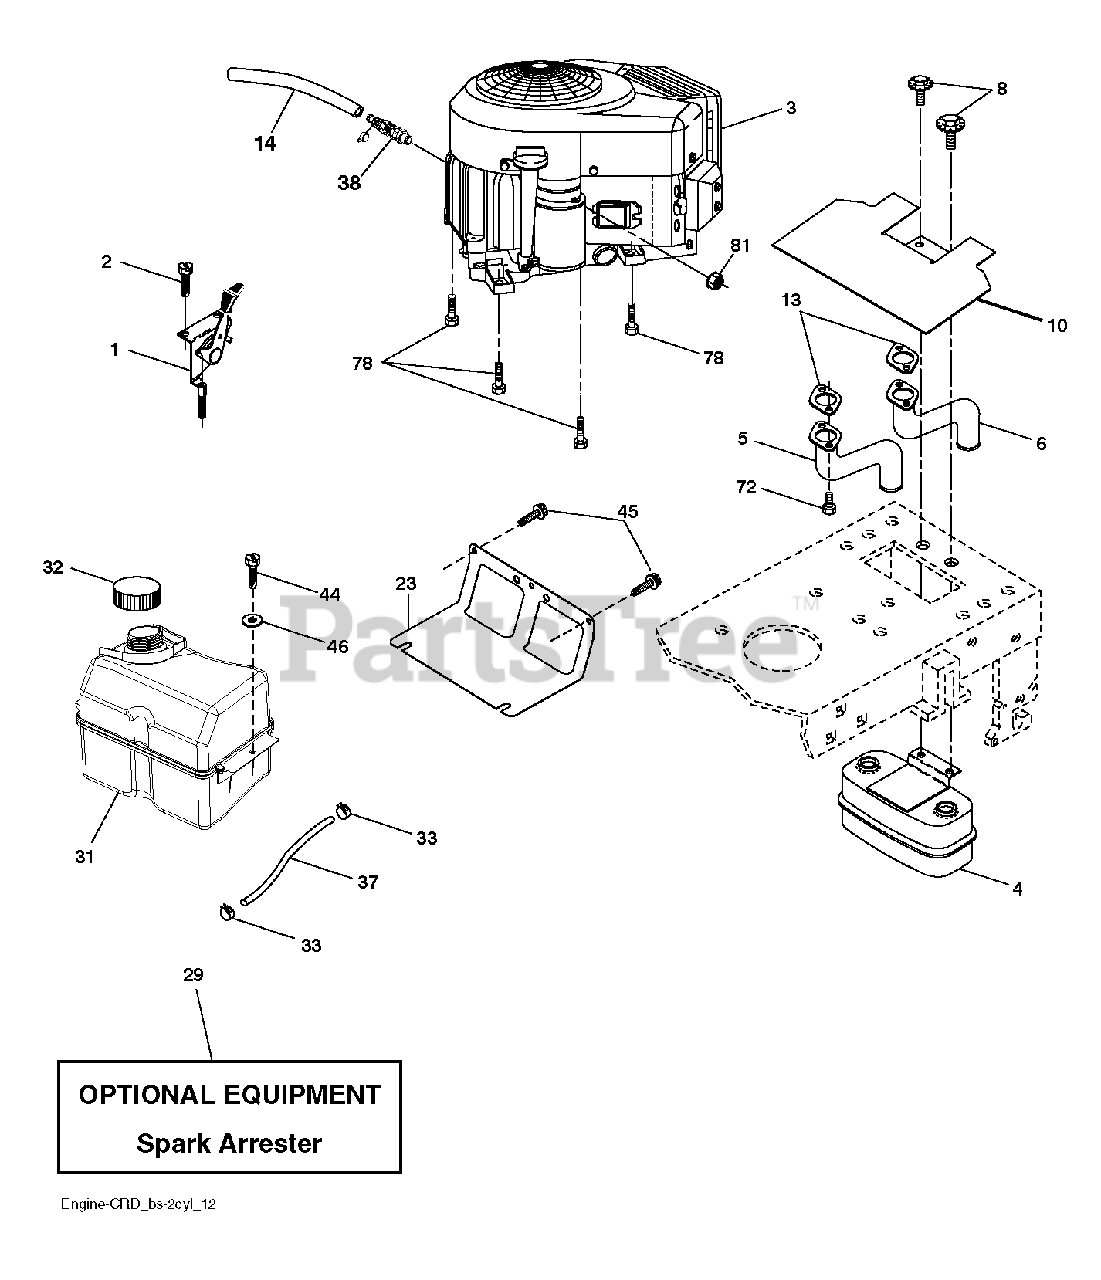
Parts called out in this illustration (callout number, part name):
1	CONTROL.TH/CK.COBRA.B&S.TWN.
2	SCREW.#10 X 0.750.BOS THREAD
4	MUFFLER.TWIN.CYL.LOW.TONE
5	EXHAUST TUBE RH
6	TUBE MANIFOLD LH
8	BOLT, 5/16-18 X 1 3/4
10	SHIELD.HEAT.MUFFLER
13	GASKET.MUFFLER
14	TUBE, DRAIN OIL ASM.
23	SHEILD.BROWNING.DBR.GUARD
29	ARRESTER SPARK (OPTIONAL)
32	CAP ASM.FUEL.2.25"FR.
33	HOSE CLAMP
37	LINE.FUEL.20
38	VALUE.OIL.DRAIN
44	SCREW HEXWSHR 1/4-20X3/4
45	SCREW, 3/8-16X3/4
72	SCREW.SOCKET.HEAD.5/16-18
78	SCREW.3/8-16
81	NUT
